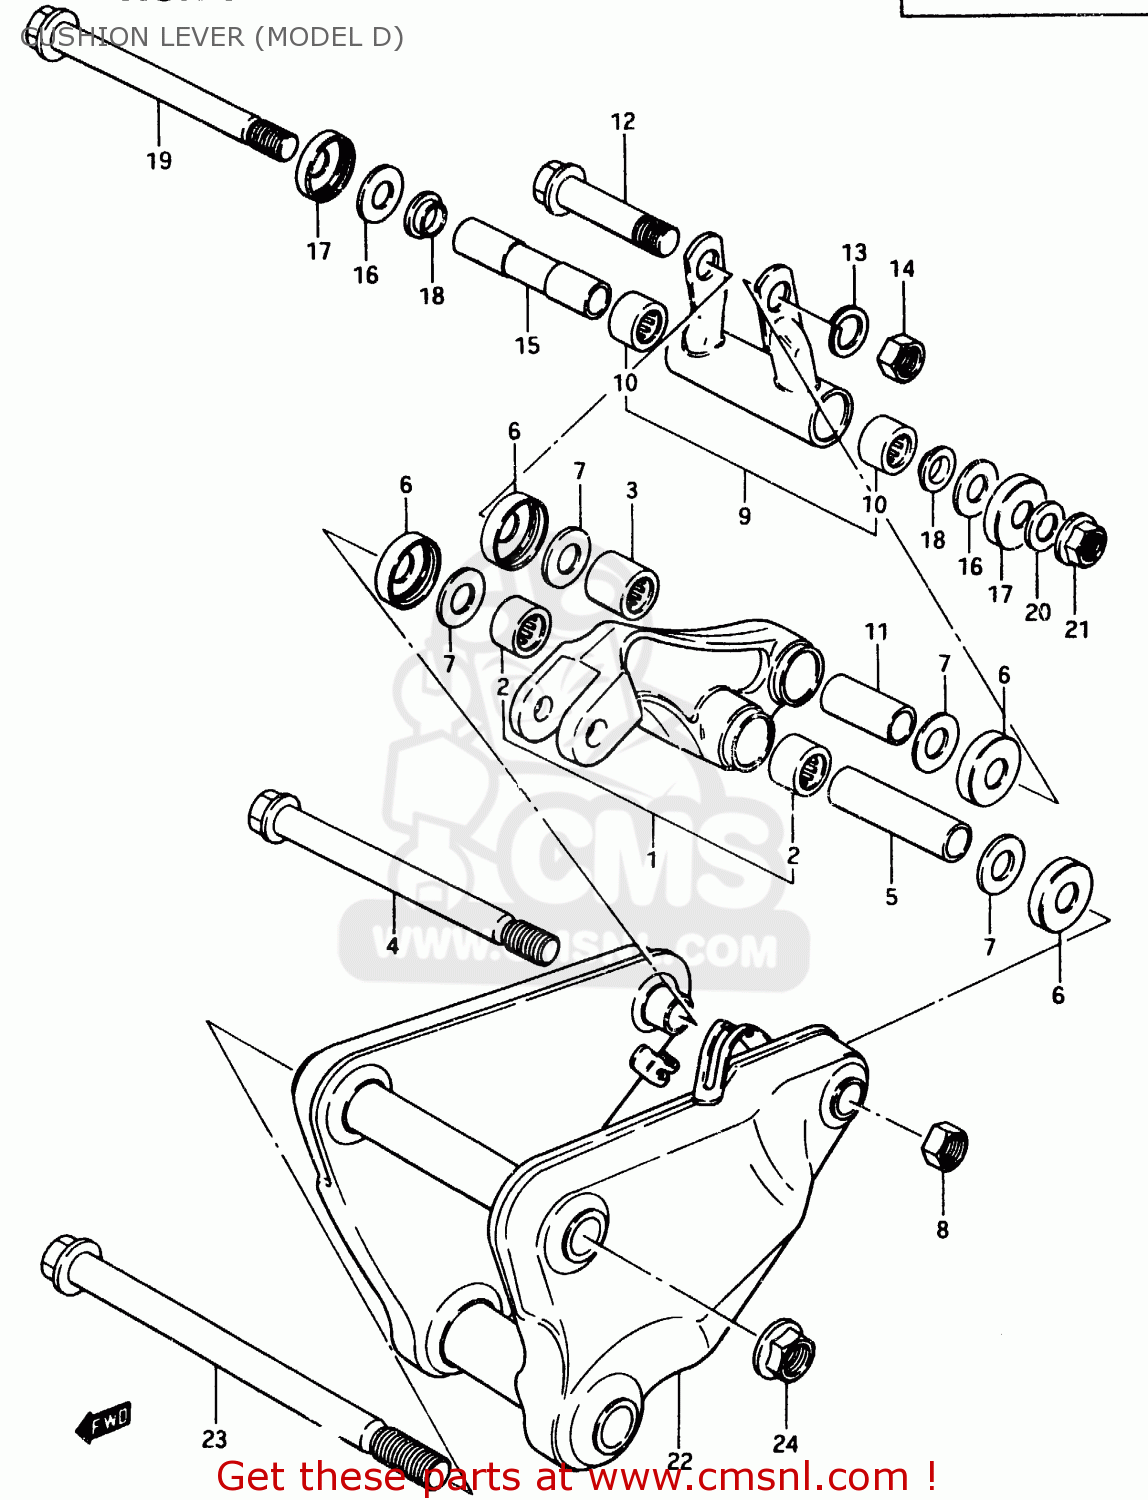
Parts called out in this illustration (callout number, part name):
1	LEVER SET,REAR CUSHION
2	ROLLER BEARING (17X24X2
3	ROLLER BEARING (17X24X25)
4	SHAFT,RR CUSHION LEVER
5	SPACER,REAR CUSHION LEVER
6	COVER,RR SWGARM DUST SEAL
7	WASHER
8	NUT
9	ROD SET,CUSHION
10	ROLLER BEARING (17X24X2
11	SPACER,RR CUSHION LEVER ROD UP
12	BOLT, UPPER
13	WASHER,LOCK 12
14	NUT
15	SPACER,RR CUSHION LVR ROD LOW
16	WASHER
17	COVER,RR SWGARM DUST SEAL
18	SPACER,REAR CUSHION ROD
19	BOLT,CUSHION ROD
20	WASHER
21	NUT
22	BRACKET,REAR SHOCK ABSORBER
23	SHAFT,SHOCK ABSORBER BRACKET
24	NUT
